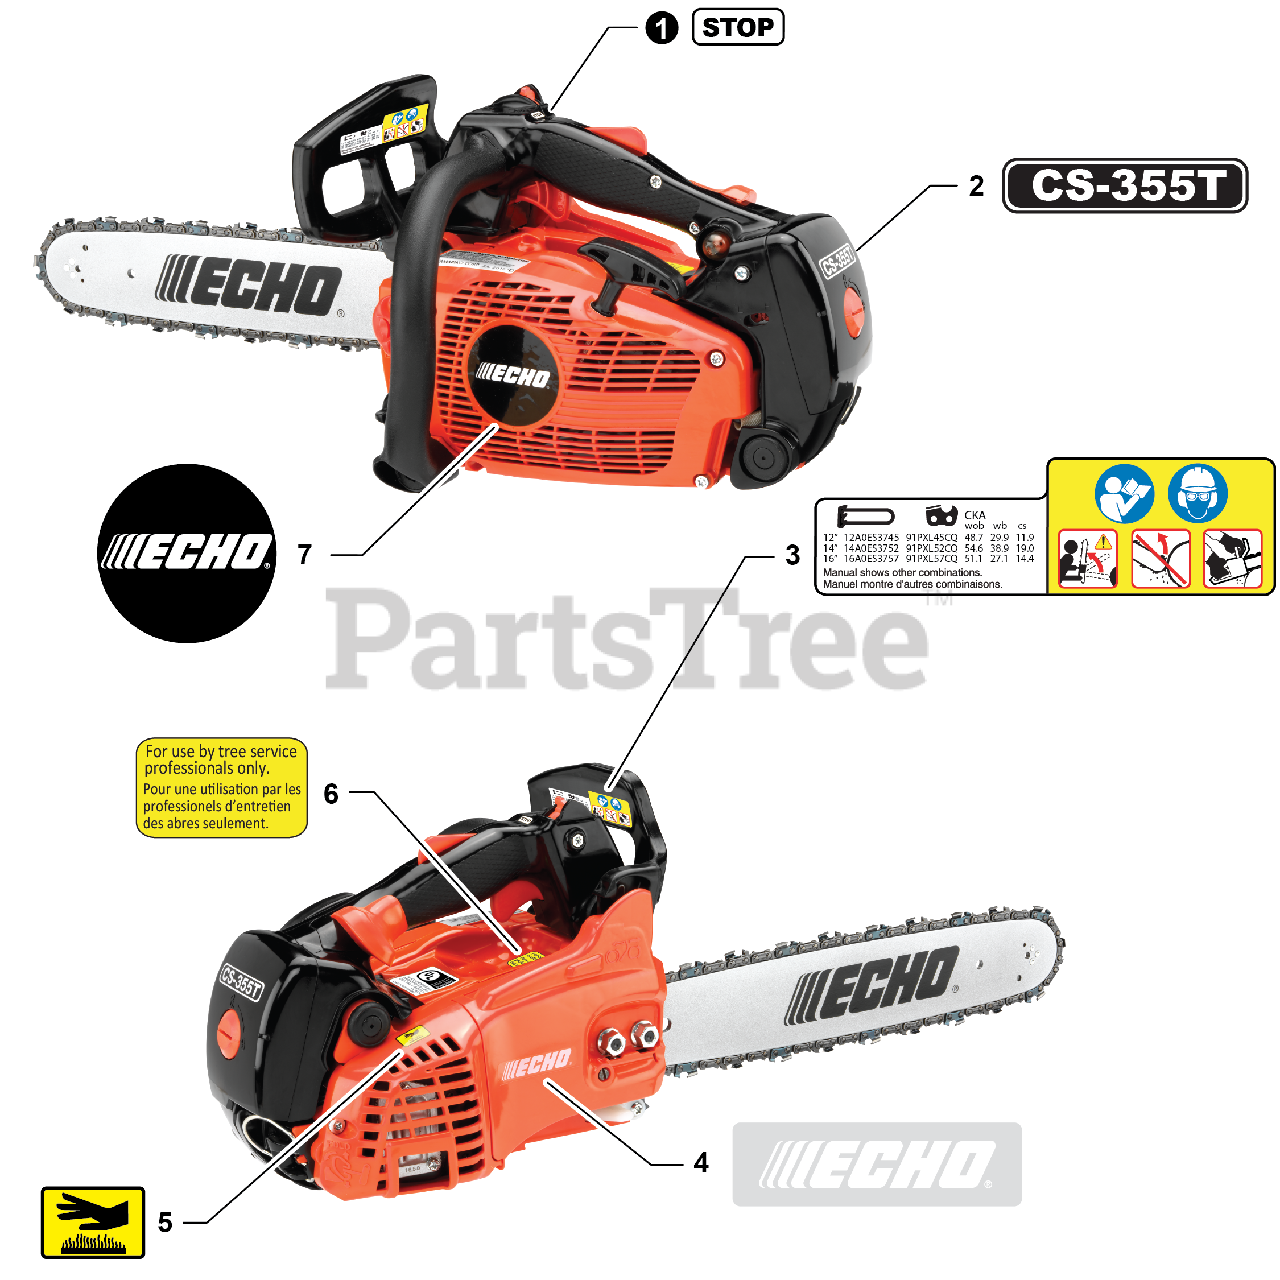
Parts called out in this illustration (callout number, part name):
1	LABEL, STOP
2	LABEL - MODEL CS-355T
3	LABEL, CAUTION
4	LABEL, ECHO
5	LABEL, CAUTION - HOT
6	LABEL, CAUTION - PROFESSIONALS ONLY
7	LABEL, ECHO
